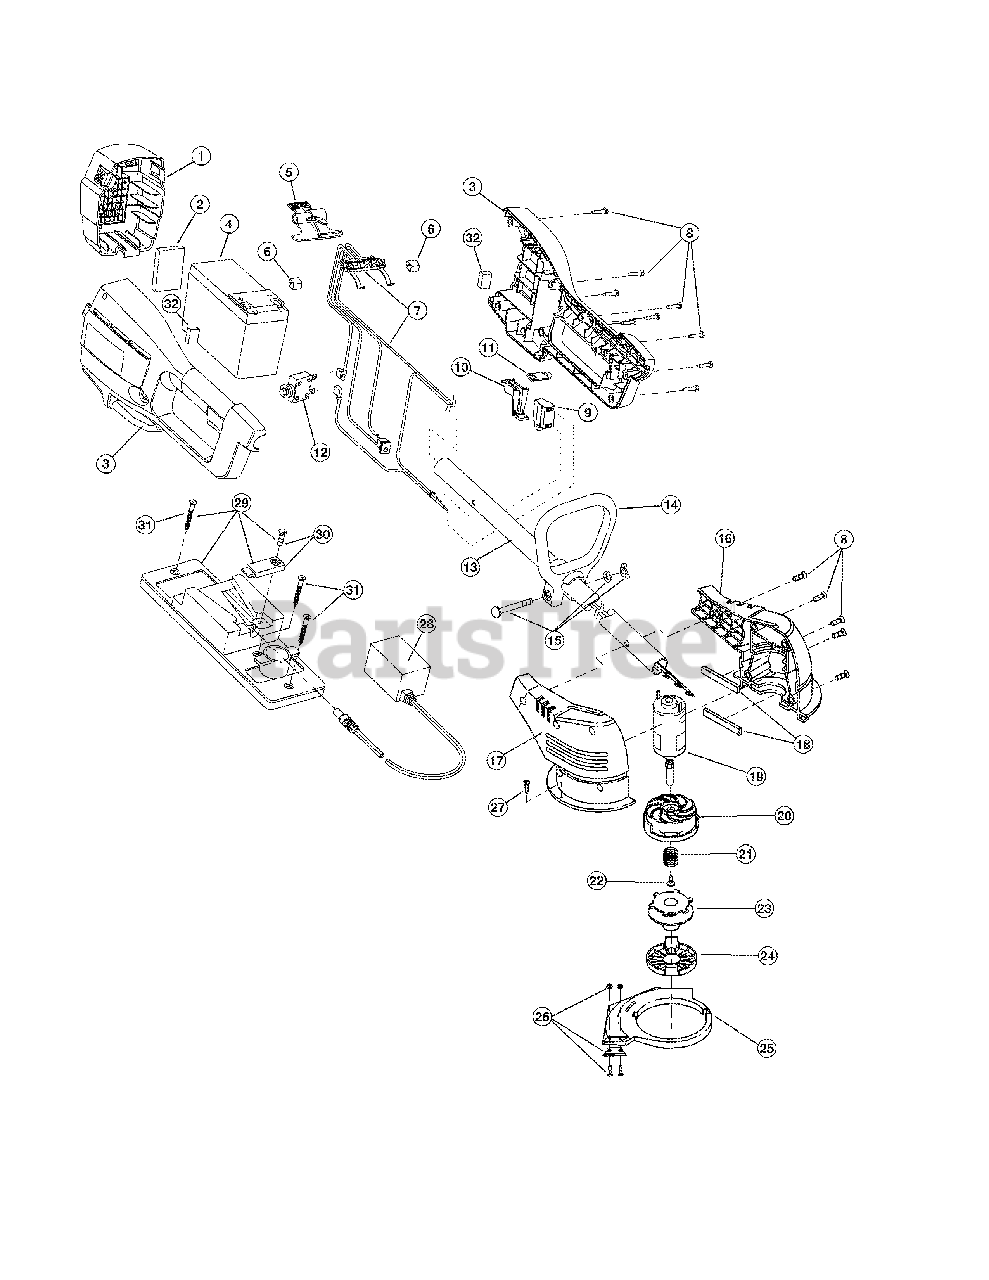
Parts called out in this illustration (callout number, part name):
1	Battery Door
3	Battery Housing
4	12 Volt Batterry
5	Battery Latch
6	Terminal Spacer
7	Wiring Harness Assembly
8	Housing Screw
9	Switch Assembly (includes 10)
11	Lock-Off Button
12	Circuit Breaker
13	Motor Wire Tube
14	D-Handle (includes 15)
15	Handle Hardware
16	Left Motor Housing
17	Right Motor Housing
19	Motor with Shaft
20	Outer Spool and Eyelet/Motor Fan
23	Inner Reel with .080" Line
24	Reel Cover
25	Guard Assembly (includes 26)
26	Blade Assembly
27	Guard Screw
28	12 Volt Charger
29	Charging Station Stand (includes 30-31)
30	Barrel Clamp with Screw
31	Mounting Screw
32	Front Battery Pads
